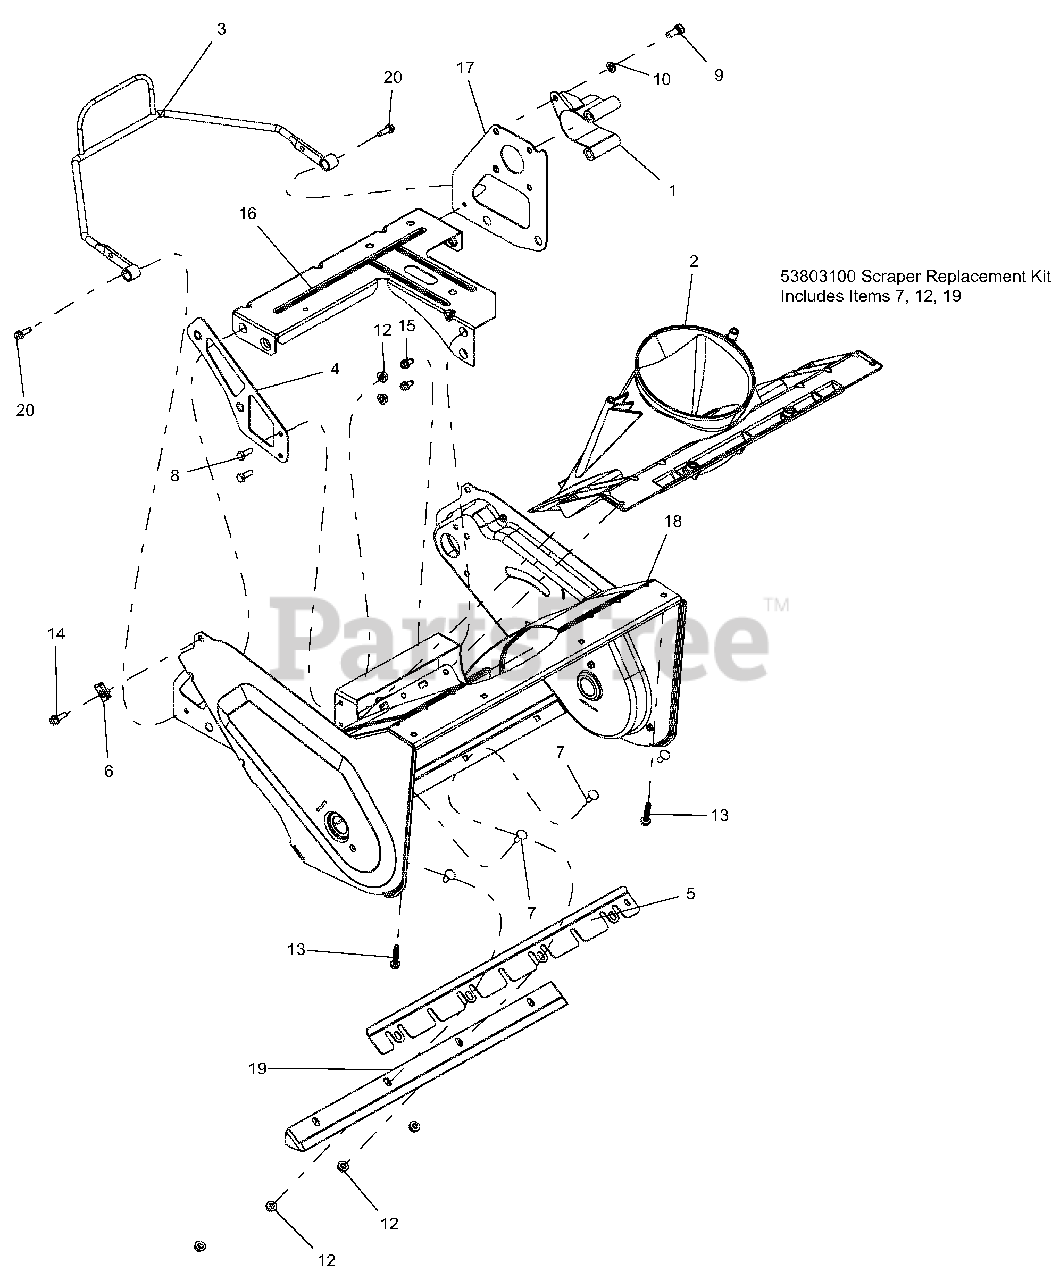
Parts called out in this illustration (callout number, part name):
1	FRAME, SPCR PTO
2	NECK, DISCHARGE
3	ENGINE, GUARD
4	FRAME, SUPPORT BRACKET
5	SCRAPER SUPPORT
6	NUT-RTNR .25-20X.56
7	@BLT-RDHDSQNK .25-20X.75 G5YZ
8	@BLT-HEX .25-20X.75 GR5 YWZC
9	BLT-HEX .31-24X.75 GR5YZ EP30
10	@WSHR-LK .31X.078 REG YWZC
12	@NUT-LK-TOP-FLG .25-20 YWZC
13	SCR-TAP .25-10X1.25 HWH YWZC
14	BLT-HEX .25-20X.75 HWH YZ GR5
15	SCR-TAP .25-20X.50 HWH TR YWZ
16	FRAME, ENGINE
17	FRAME, DRIVE BRACKET
18	WLDMT, FRAME
19	KIT, SCRAPER REPLACEMENT
20	SCR-TAP-PM .25-20X.75 TR YWZ
